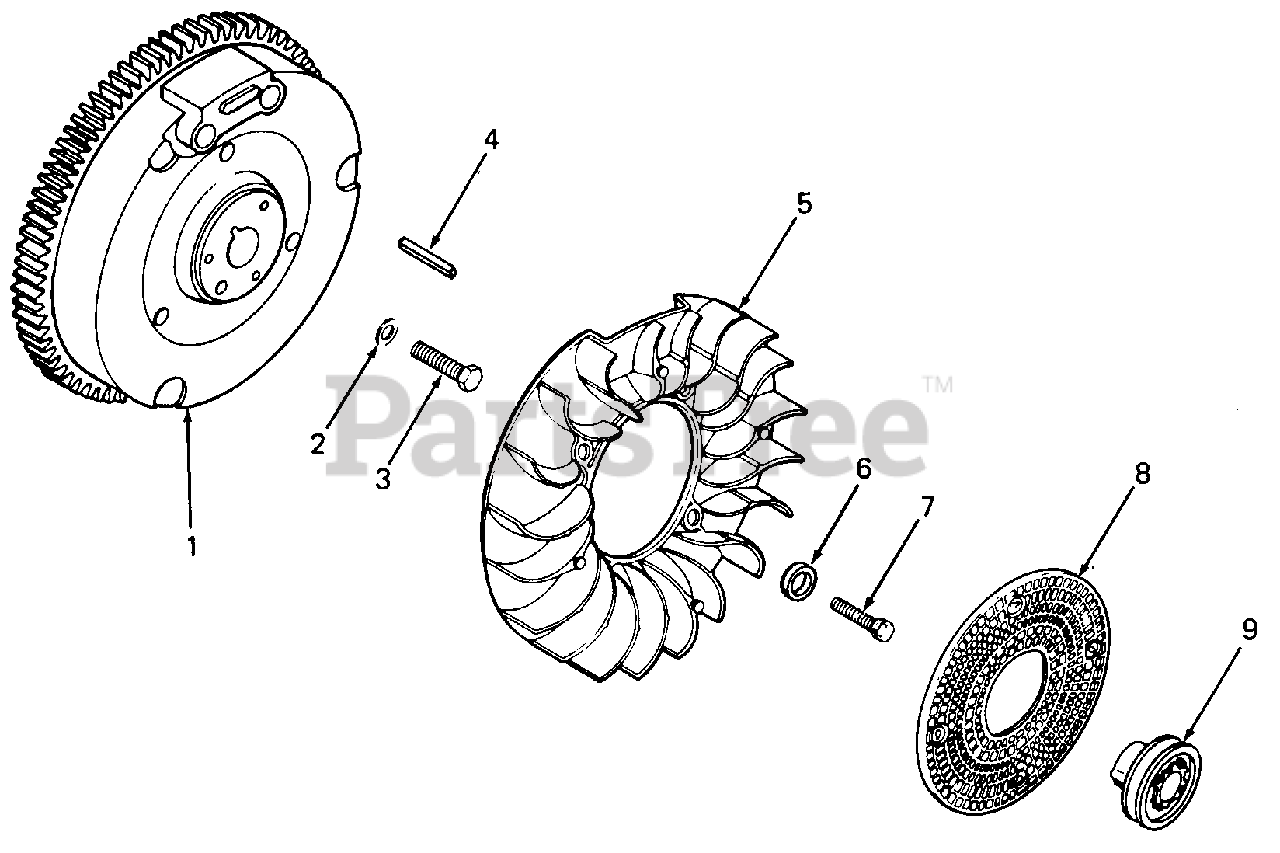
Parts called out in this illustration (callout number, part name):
2	Washer
3	Screw, Hex Mach, 3/8-24 X 1.25 Lg
4	Key, Square, 3/16 X 1.37
7	Screw, Hex Wash Hd, 1/4-20 X .62 Lg
8	Screen, Grass
9	Kit, Drive Cup
